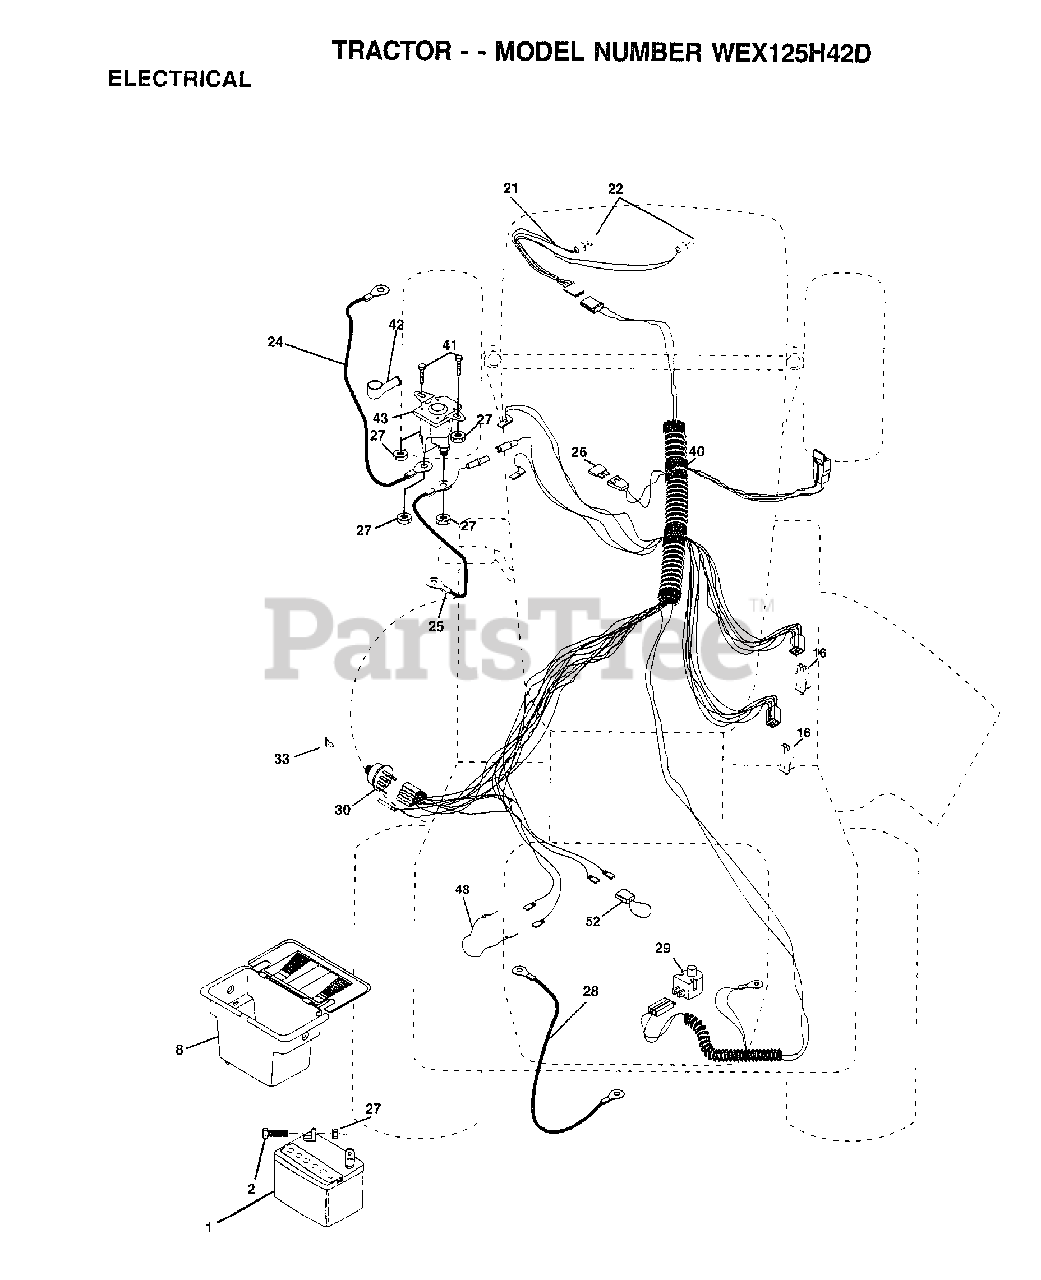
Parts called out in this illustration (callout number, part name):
2	BOLT LT
8	"CASE,BATTERY.MECH"
16	SWITCH INTERLOCK
21	HARNESS.ASM.LIGHT W/4152J
22	HEADLAMP BULB
24	"CABLE T, BATTERY"
25	CABLE.BTRY.6GA.RD
26	FUSE.15 AMP
27	NUT
28	CABLE T
29	SWITCH SEAT
30	SWITCH.IGN.
33	KEY MLD GEN DELTA
40	HARNESS IGN
41	BOLT HXHD FIN
48	ADAPTER AMMETER
52	PROTECTION LOOP
